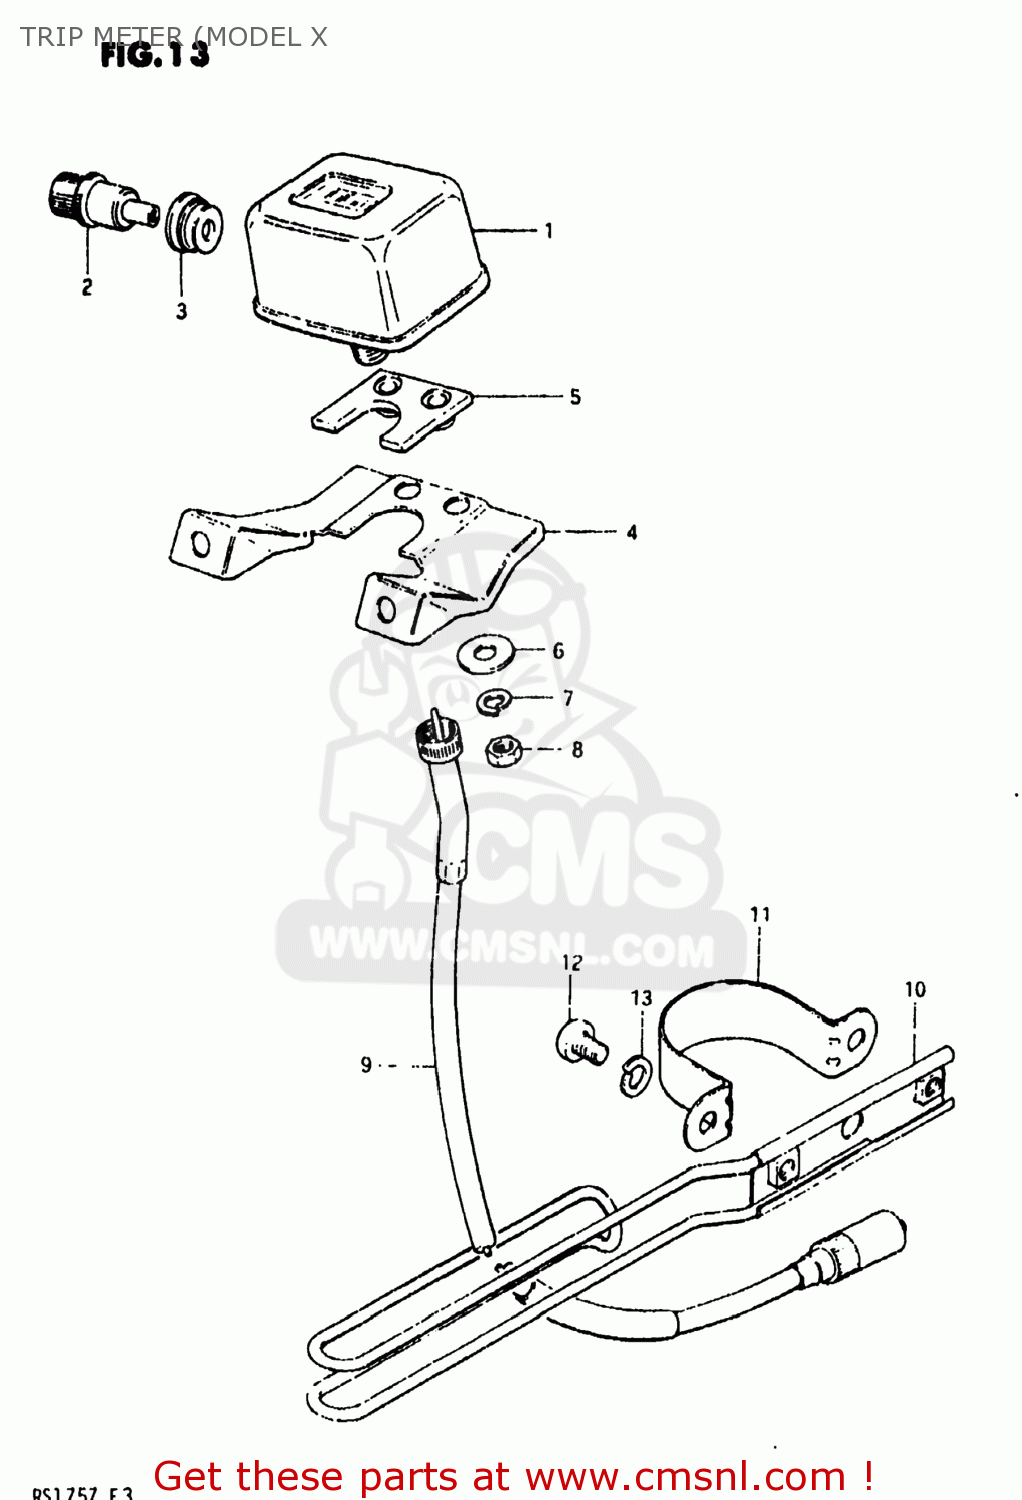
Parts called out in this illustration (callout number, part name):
1	TRIP METER
2	KNOB,TRIP METER
3	COVER,TRIPMETER KNOB
4	BRACKET,TRIPMETER
5	CUSHION,TRIPMETER
6	WASHER,METER
7	LOCK WASHER
8	NUT
9	CABLE ASSEMBLY,SPEEDOMETER
10	CLAMP,SPEEDOMETER CABLE
11	CLAMP
12	SCREW 6X12
13	LOCK WASHER
